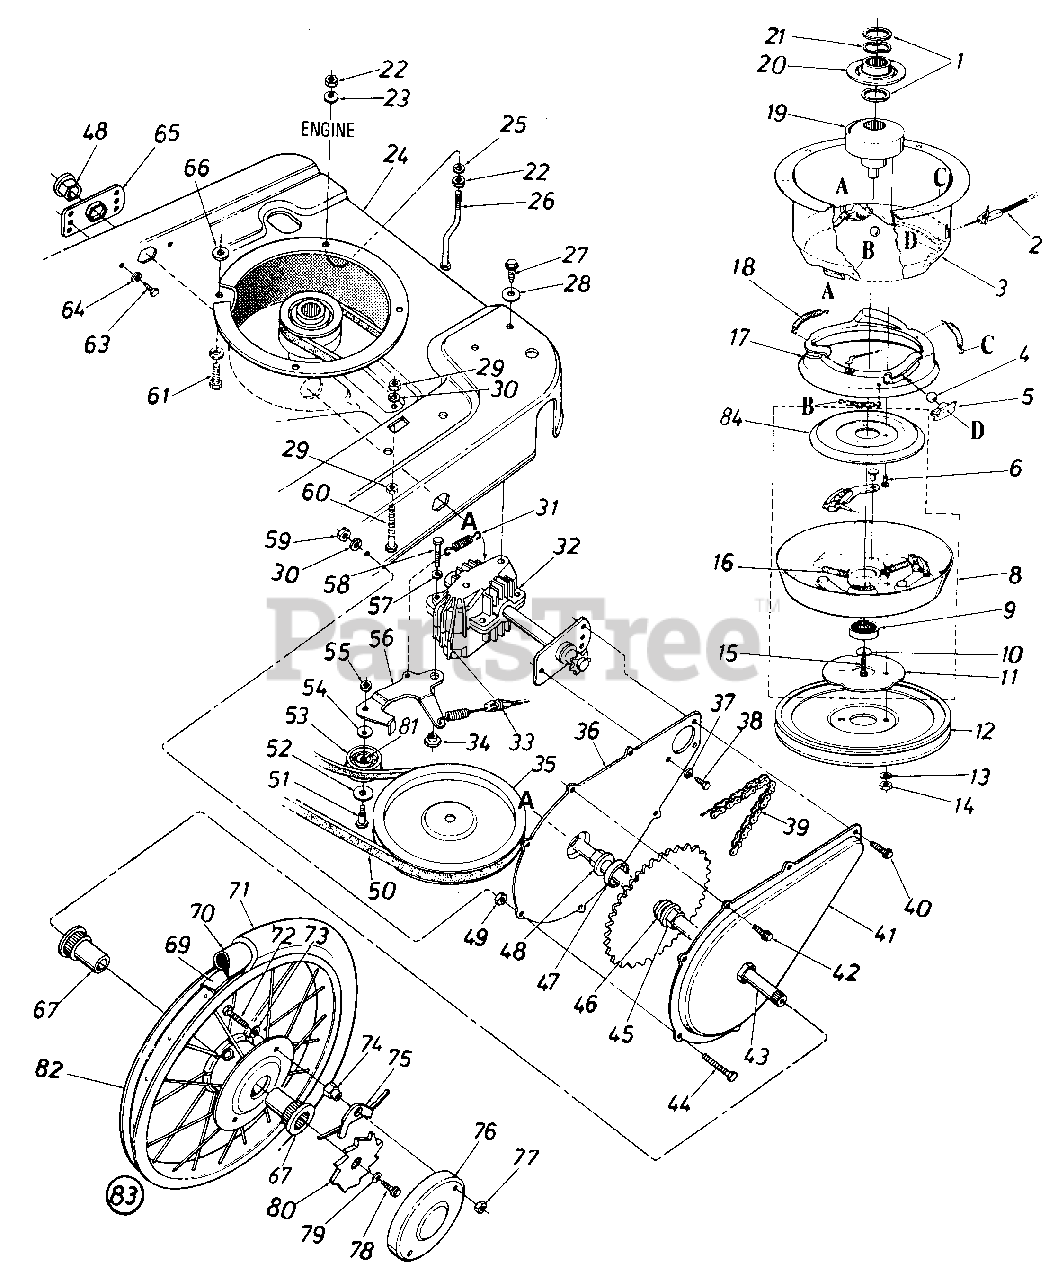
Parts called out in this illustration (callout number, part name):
1	WASHER-SERRATED
2	CABLE-CLUTCH
3	HOUSING-CLUTCH
4	BALL-STEEL
5	BALL-BLOCK
6	SCREW-HEX WASH SF TAPP
8	HOUSING-CLUTCH MBC
9	BEARING-BALL
10	WASHER-BELL
11	HOUSING ASSY-W/FPA
12	PULLEY-5/8-V
13	WASHER-LOCK-3/8
14	NUT-HEX 3/8-24
15	SCREW-HEX 7/16 N.F. X 2 GR.5
16	SPRING-COMPRESSION
17	CONE-BRAKE CUP
18	SPRING-EXTENSION
19	ADAPTER-FIXED PULLEY
20	PULLEY-MOVABLE
21	WASHER-WAVE
22	NUT-HEX 5/16-18
23	WASHER-BELL .337 X .867 X .057
24	FRAME-HI WHEEL
25	WASHER-LOCK-5/16
26	GUARD-BELT-5/16 BOLT
27	SCREW-HEX WASH HD 5/16-18X1/2
28	WASHER-BELL .3/8ID X 1.12OD X .030
29	NUT-HEX 1/4-20
30	LOCK WASHER 1/4 DIA
31	SPRING-EXTENSION
32	TRANSMISSION-COMP
33	CABLE-CLUTCH X 50.0
34	SPACER-SHLD
35	PULLEY
36	COVER-CHAIN-45T
37	LOCK WASHER 1/4 DIA
38	SCREW-HEX B-TAP 1/4 X .38
39	#48 CHAIN 1/2 PITCH X 51 LINKS
40	SCREW-HEX WASH SF TAPP
41	CASE-CHAIN-45T
42	SCREW-HEX B-TAP 1/4 X .38
43	AXLE ASSY-RR
44	SCREW-HEX 1/4-28 X .88
45	BEARING-HEX FLANGE
46	WASHER-FL-.640 ID X .94 OD
47	SPACER-.630 X 1.250 OD
48	BEARING-HEX FLANGE
49	NUT-HEX JAM 1/4-28
50	BELT-V- 3/8 X 28
51	SCREW-SHLD
52	WASHER-FL .995 X .032
53	KIT-PULLEY
54	WASHER-SPRING BELL
55	NUT-HEX 1/4-28
56	BRACKET ASSY-IDLER
57	LOCK WASHER 1/4 DIA
58	SCREW-HEX 1/4-20 X 1.25
59	NUT-HEX 1/4-28
60	SCREW-HEX 1/4-20 X 2.00
61	SCREW-HEX R
63	SCREW-HEX B-TAP 1/4 X .38
64	LOCK WASHER 1/4 DIA
65	BEARING-CUP HEX
66	WASHER-FL-.406 ID X .74 OD X .063
67	BEARING-FLANGE
69	RIM STRIP
70	TUBE-16 X 2.12
71	TIRE-16 X 2.125
72	SCREW-HEX 5/16-18 X 1.00
73	WASHER-INTERN L 5/16
74	NUT-HEX 5/16-18 SPEC
76	COVER-WHEEL
77	NUT-HEX 5/16-18
78	SCREW-TAP
79	WASHER-SPRING BELL
80	RACHET-WHEEL
81	BEARING-NEEDLE
82	WHEEL RIM 16.0 X 2.1
83	WHEEL ASSY W/TIRE 16 X 2.12
84	CONE-CLUTCH
